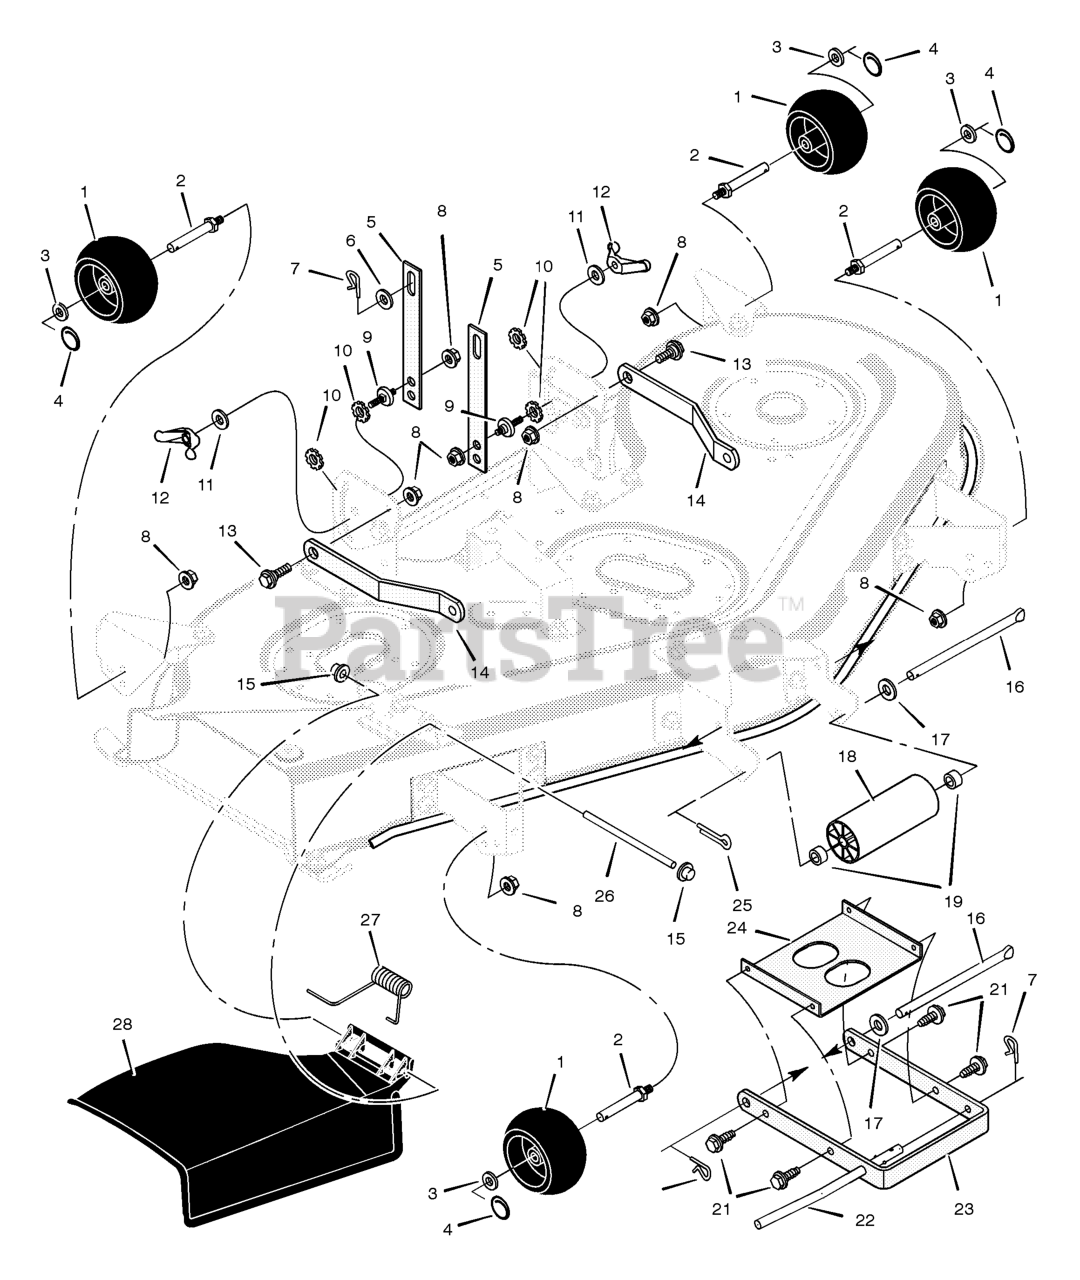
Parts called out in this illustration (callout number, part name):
1	Wheel, Gage
2	BOLT, Gauge Wheel
4	Pin, Hair
5	Link, Lift
7	Pin, Hair
8	Locknut
9	Pin, Hanger
12	Wingnut
13	Bolt, Shoulder
14	Bracket, Rear Suspension
15	Cap, Push
16	Rod, Deck Suspension
22	Rod, Hanger
23	Bracket, Front Suspension
24	Stiffener
25	Pin, Cotter
26	Rod, Deflector
27	Spring, Torsion
28	Deflector, Chute
